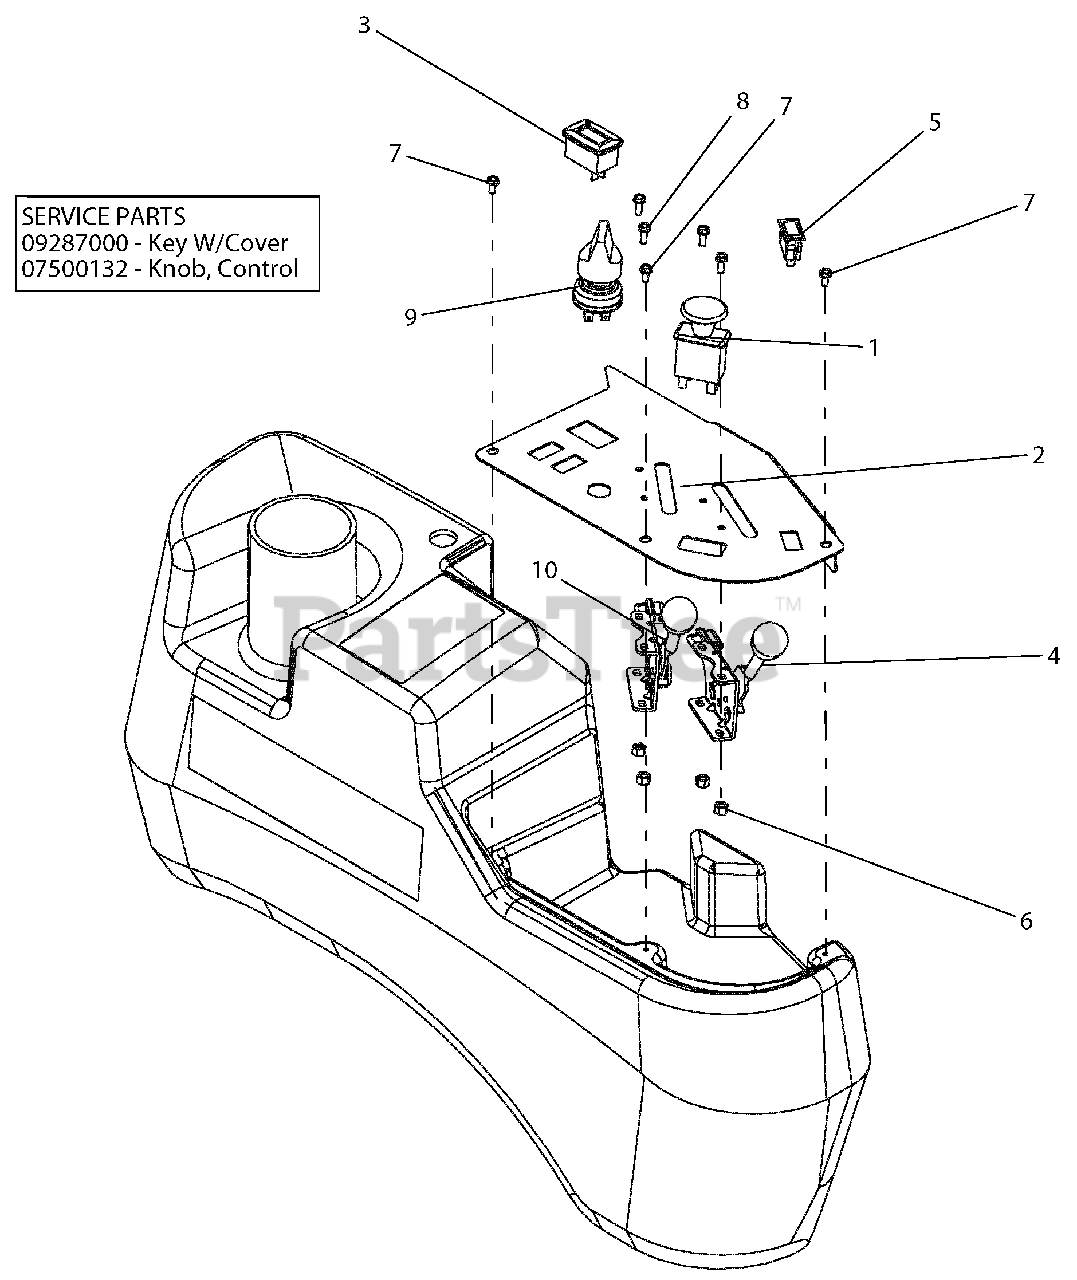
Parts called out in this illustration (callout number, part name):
1	SWITCH, CLUTCH
2	PANEL, CONTROL-BLACK
3	METER, HOUR W/MAINTENANCE
4	CABLE, PRO-CONTROL THROTTLE
5	LIGHT, INDICATOR
6	NUT-LK-NYL #10-24 YWZC
7	SCR-MCH 10-24X.38 HWHSTAINLESS
8	@SCR-MCH 10-24X.50 HWH YWZC
9	SWITCH, IGNITION
10	CABLE, PRO-CONTROL THROTTLE
